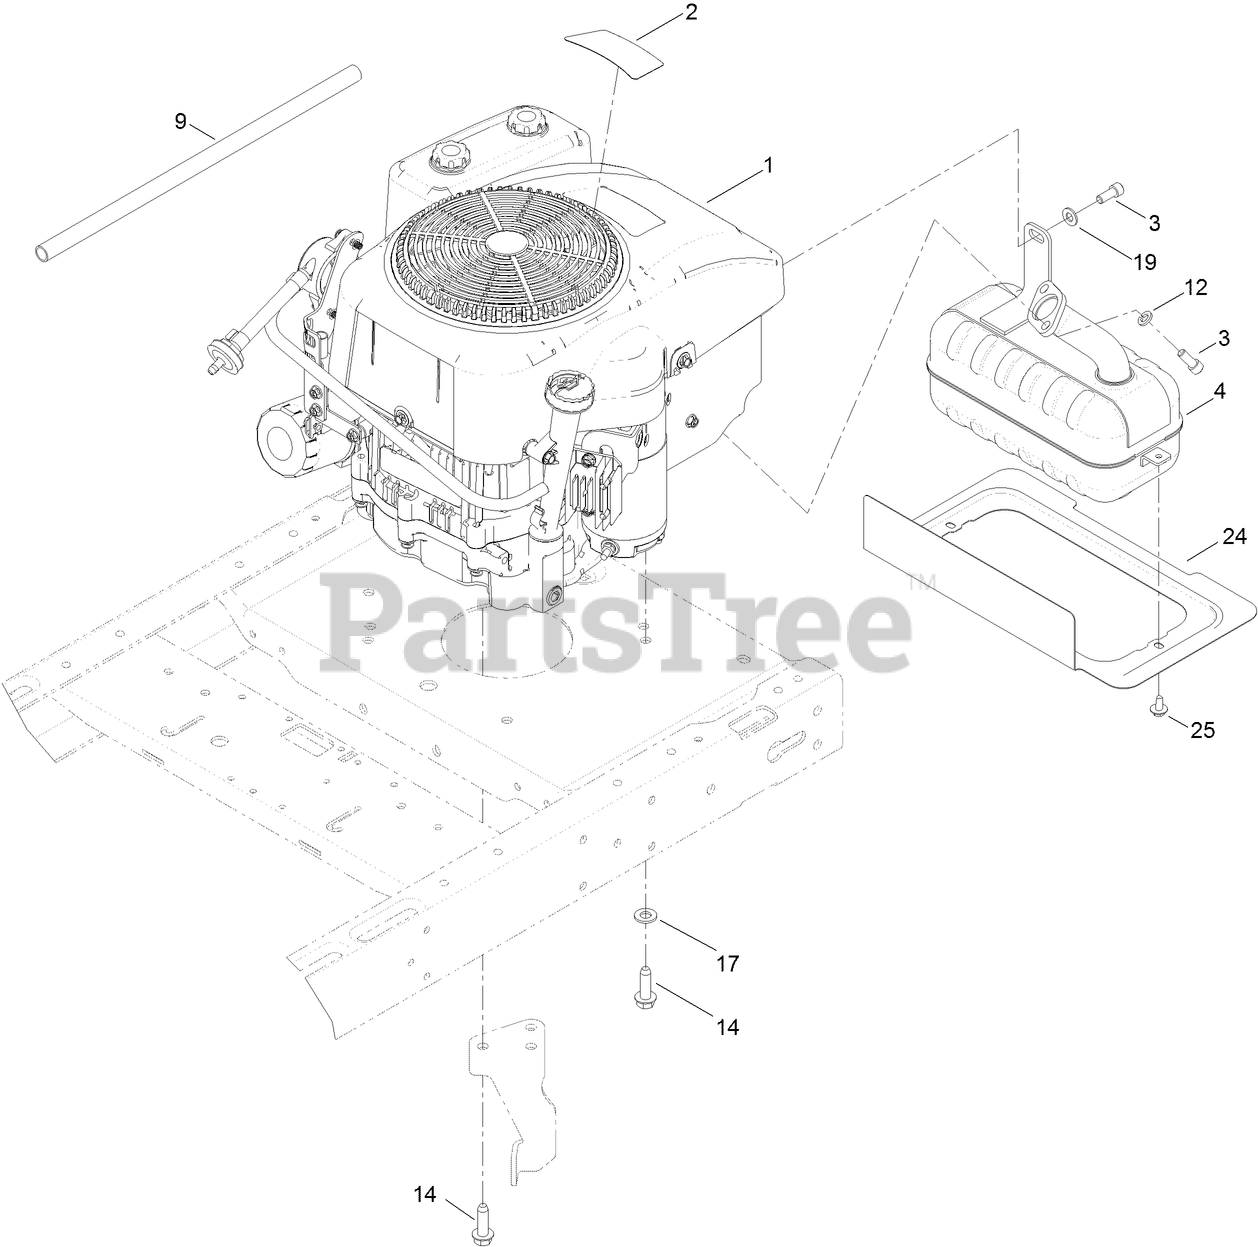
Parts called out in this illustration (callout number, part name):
1	ENGINE-LC1P92F-1
2	DECAL-ENGINE
3	SCREW-HSH
4	MUFFLER
9	TUBE-DRAIN, OIL
12	WASHER-LOCK
14	SCREW-TAPTITE
17	WASHER-FLAT
19	WASHER-PLAIN
24	SHIELD-HEAT
25	SCREW-HHFTF
